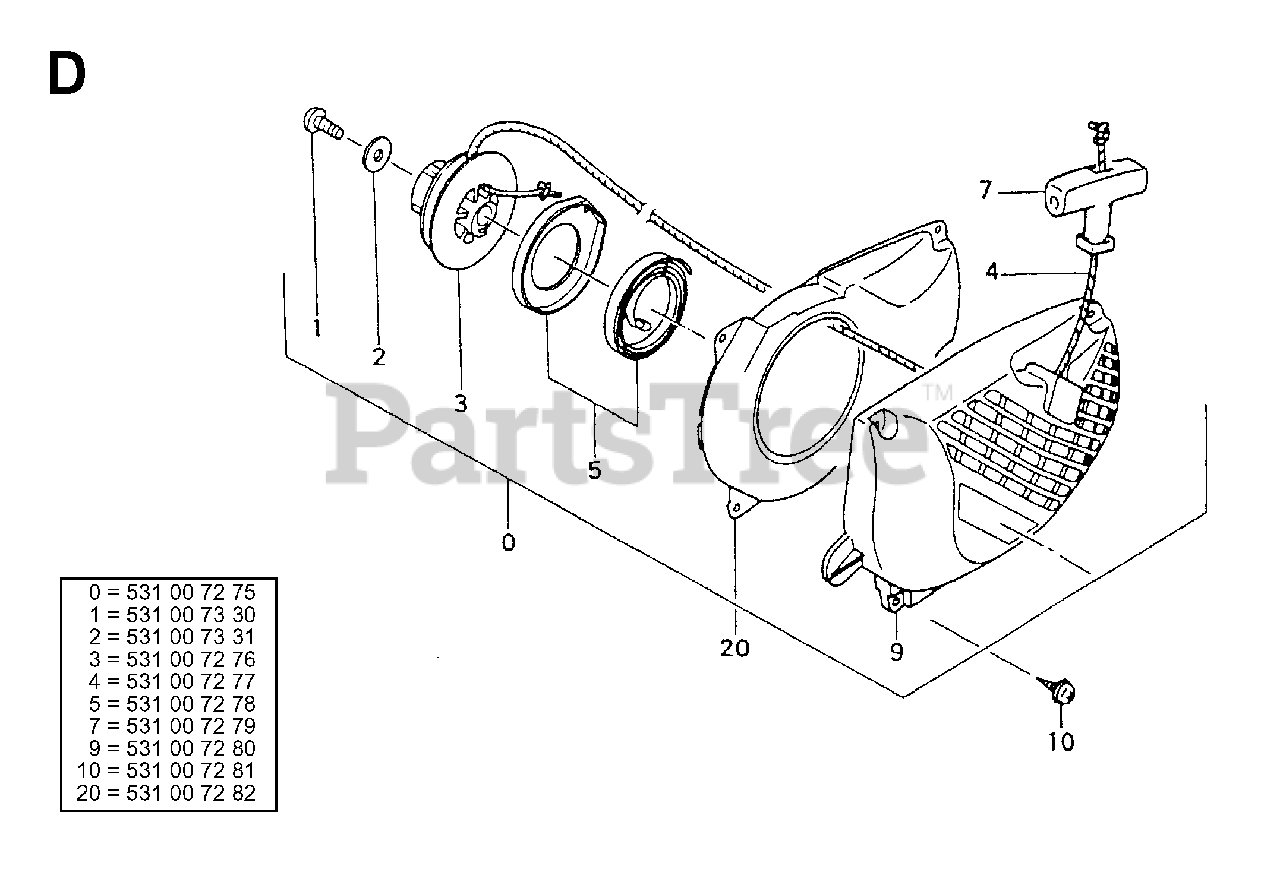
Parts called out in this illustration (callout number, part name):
3	STARTER PULLEY
4	STARTER ROPE
5	RETURN SPRING
9	STARTER HOUSING
20	AIR CONDUCTOR
